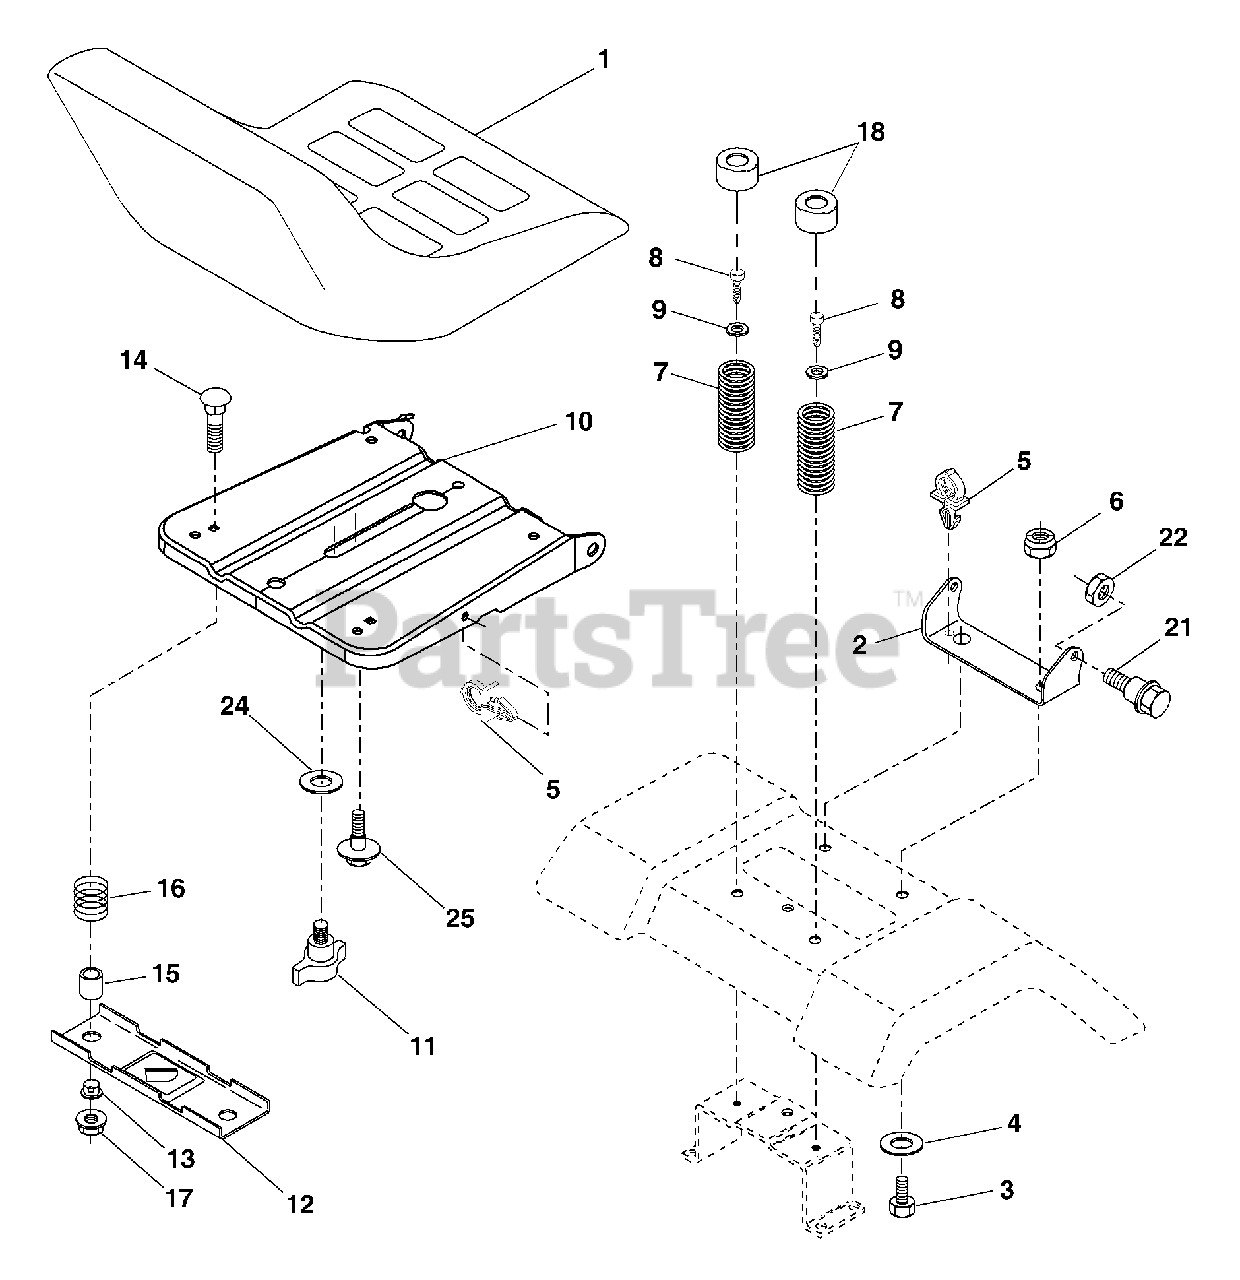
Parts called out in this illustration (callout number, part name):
1	Seat
2	Bracket Pivot Seat
3	Bolt Fin Hex 3/8-16 unc x 1
4	Washer 13/32 x 1 x 10 Ga.
5	Clip Push-In
6	Nut Hex w/Ins. 3/8-16 unc
7	Spring Seat Cprsn
8	Screw 3/8-16 x 1-1/2
9	Washer 13/32 x 1 x 14 Ga.
10	Pan Seat
11	Knob Seat Adj. Wingnut
12	Bracket Mounting Switch
13	Bushing Snap Blk Nyl 50 Id
14	Bolt Rdhd Sqnk 1/4-20 x 1-1/2
15	Spacer Split 28x .88 Zinc
16	Spring Cprsn Plate 1.310 Ga.
17	Nut Lock 1/4 Lge Flg Gr. 5 Zinc
18	Cap Spring Seat
21	Bolt Shoulder 5/16-18 unc
22	Nut Hex Lock W/Ins 5/16-18
24	Washer 17/32 x 1-3/16 x 12 Ga.
25	Bolt Shoulder 5/16-18 x 62
